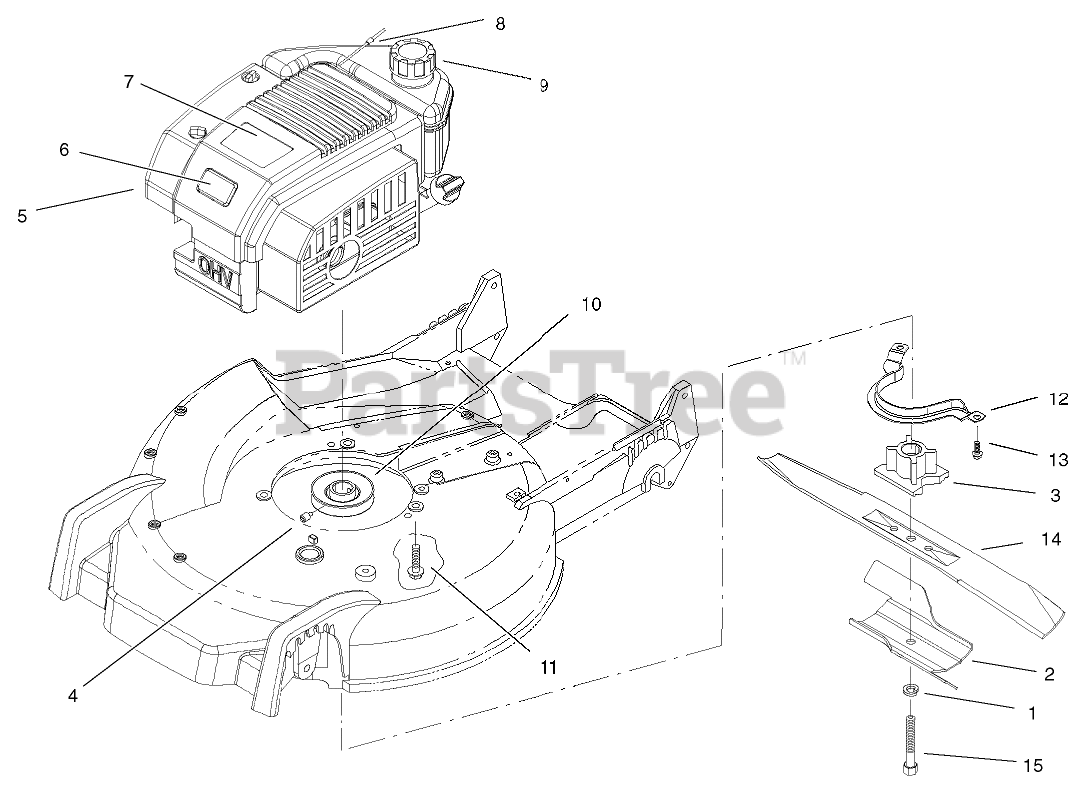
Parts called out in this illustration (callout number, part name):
1	WASHER-LOCK
2	ACCELERATOR-BLADE
3	RETAINER-BLADE
4	SCREW-SET
6	Decal
7	DECAL - RECOIL
8	STOP-ROPE
9	GAS CAP ASM
10	PULLEY ASM
11	SCREW-HWH
12	GUIDE-BELT
13	SCREW-HWHTF
14	BLADE
15	SCREW-BLADE
